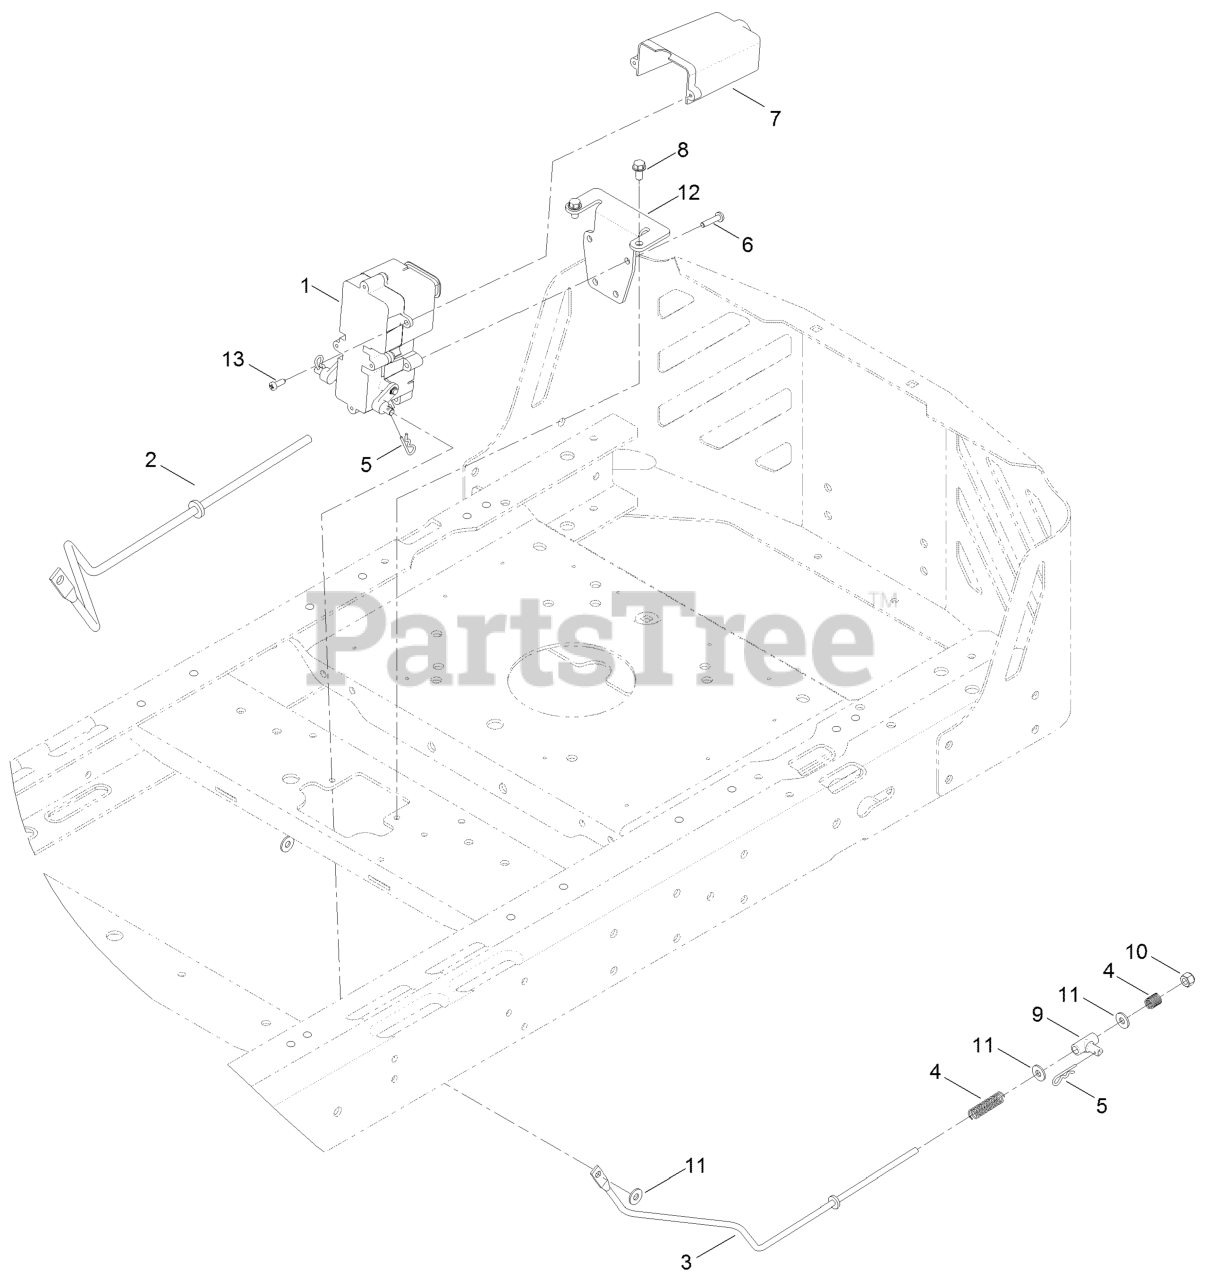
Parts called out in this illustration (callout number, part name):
2	ROD-BRAKE, RH
3	ROD-BRAKE, LH
4	SPRING-COMPRESSION
6	SCREW-PPH
8	SCREW-HWH
9	MOUNT-PIVOT
10	NUT-LOCK, NI
12	BRACKET-MOUNT, BRAKE
13	SCREW-PPH
